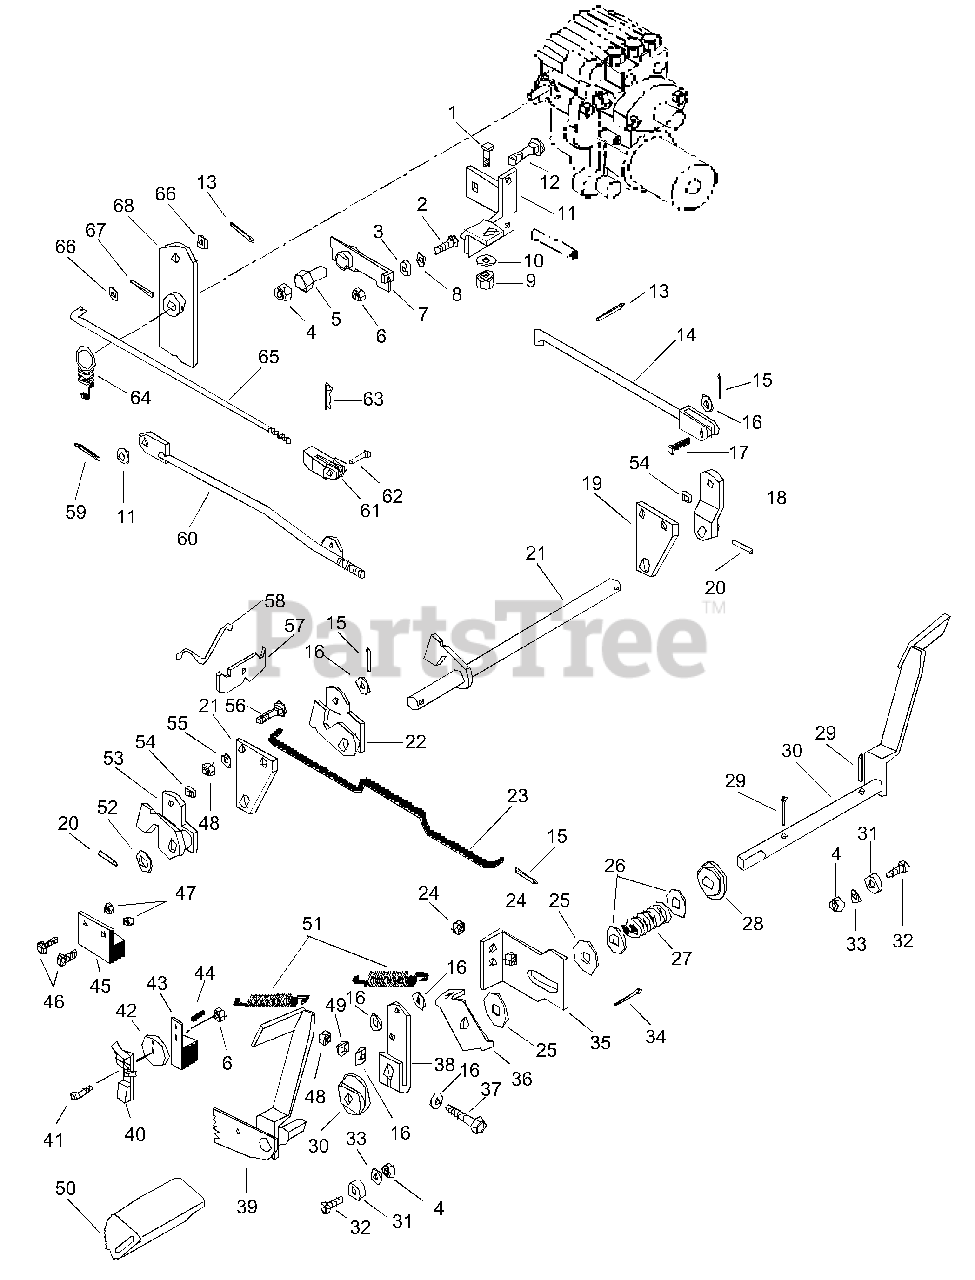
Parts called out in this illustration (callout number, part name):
1	Bolt-Round Head Square Neck .500-13 x .25 Grade 5
2	Bolt-Hex .25-20 x 1.00 Grade 5
3	Bearing Ball Double .250 x .638 x .438
4	Nut-Locking-Center .312-18
5	Eccentric
6	Nut-Locking-Center .250-20
7	Detent Arm
8	Washer-Flat-Steel .281 x 1.250 x .048
9	Nut-Locking .50-13
10	Washer-Flat-Steel .531 x 1.06 x .095
11	Mount Weldment
12	Bolt-Round Head Square Neck .31-18 x 2.25
13	Pin-Cotter .09 x .75
14	Brake Rod
15	Pin-Cotter .12 x .75
16	Washer-Flat-Steel .406 x .812 x .065
17	Clevis Pin .370/.375 x 1 1/8
18	Brake Arm
19	Plate
20	Pin-Groove .250 x 1.25
21	Brake Shaft
22	Arm
23	Brake Rod
24	Nut-Locking-Center .50-13
25	Washer-Flat-Steel .755 x 2.000 x .125
26	Washer-Flat-Steel .755 x 1.375 x .062
27	Spring-Compression .148 x 1.23 x 2.53
28	Bushing-Flange .750 x 1.750 x .875 x 2.125
29	Pin-Cotter .18 x 1.25
30	Left Hand Lever
32	Bolt-Hex .31-18 x .875 Grade 5
33	Washer-Flat-Steel .38 x .875 x .083
34	Pin-Cotter .09 x 1.0
35	Neutralizer Plate
36	Neutralizer Arm
37	Bolt-Hex .38-16 x 2.25 Grade 5
38	Arm - Brake
39	Right Hand Lever
40	Brake Latch
41	Bolt-Hex .25-20 x .75 Grade 5
43	Actuator, Switch
44	Roll Pin
45	Switch-Interlock
46	Screw-Machine 10-24 x .75
47	Nut-Locking-Nylon 10-24 with Insert
48	Nut-Hex .38-16 Grade 2
49	Washer-Lock .38 x .094
50	Pedal Cover
51	Spring-Tension .090 x .75 x 3.50
52	Washer-Flat-Steel .754 x 1.125 x .062
53	Brake Arm
54	Grommet .125 x .375
55	Washer-Lock .375 x .130
56	Bolt-Round Head Square Neck .38-16 x 1.0
57	Balance Link
58	Clip
59	Pin-Cotter .12 x 1.0
60	Neutralizer Rod
61	Yoke .31-24 x 2.250
62	Pin-Clevis .312 x .822
63	Pin-Hair Internal .08 x .18 x 1.18
64	Spring-Tension .080 x .75 x 2.81
65	Shift Rod
66	Washer-Flat-Steel .323 x .625 x .062
67	Pin-Roll .250 x 1.38
68	Shift Arm
